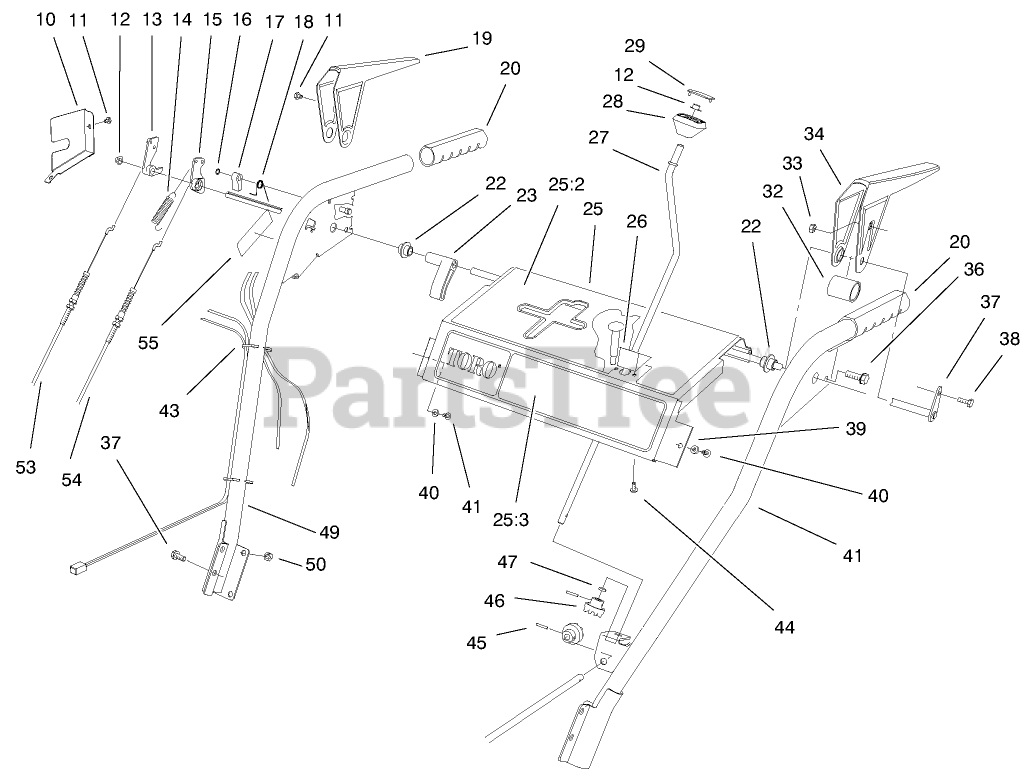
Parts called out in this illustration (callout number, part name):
10	COVER-LOCK, LEVER
12	NUT-PUSH
14	SPRING-EXTENSION
15	CAM-RELEASE
16	RING-RETAINING
17	LATCH-LOCKING
18	SPRING-TORSION
19	LEVER-TRACTION, RH
20	GRIP-HANDLE
22	BUSHING-LEVER
23	LEVER-TRIP
25:2	DECAL-CONTROL
25:3	DECAL-FRONT PANEL (824)
26	PLATE-GUIDE
27	CRANK-ROD, CHUTE
28	KNOB-CONTROL, CHUTE
29	COVER-KNOB
32	SPACER-LEVER, TRACTION
33	NUT-LOCK, NI
34	LEVER-TRACTION, LH
36	SCREW-HWHTF
37	CROSS ROD ASM
38	SCREW-HWH
39	WASHER-FLAT
40	SCREW-HWHTF
41	LH HANDLE ASM, 24"-32"
43	TIE-CABLE
44	SCREW
45	PIN-SPRING
46	GEAR-UNIVERSAL
47	WASHER-RUBBER
49:2	DECAL-ADJUSTMENT
50	NUT-LOCK, NI
53	CABLE-IMPELLER
54	CABLE-TRACTION
